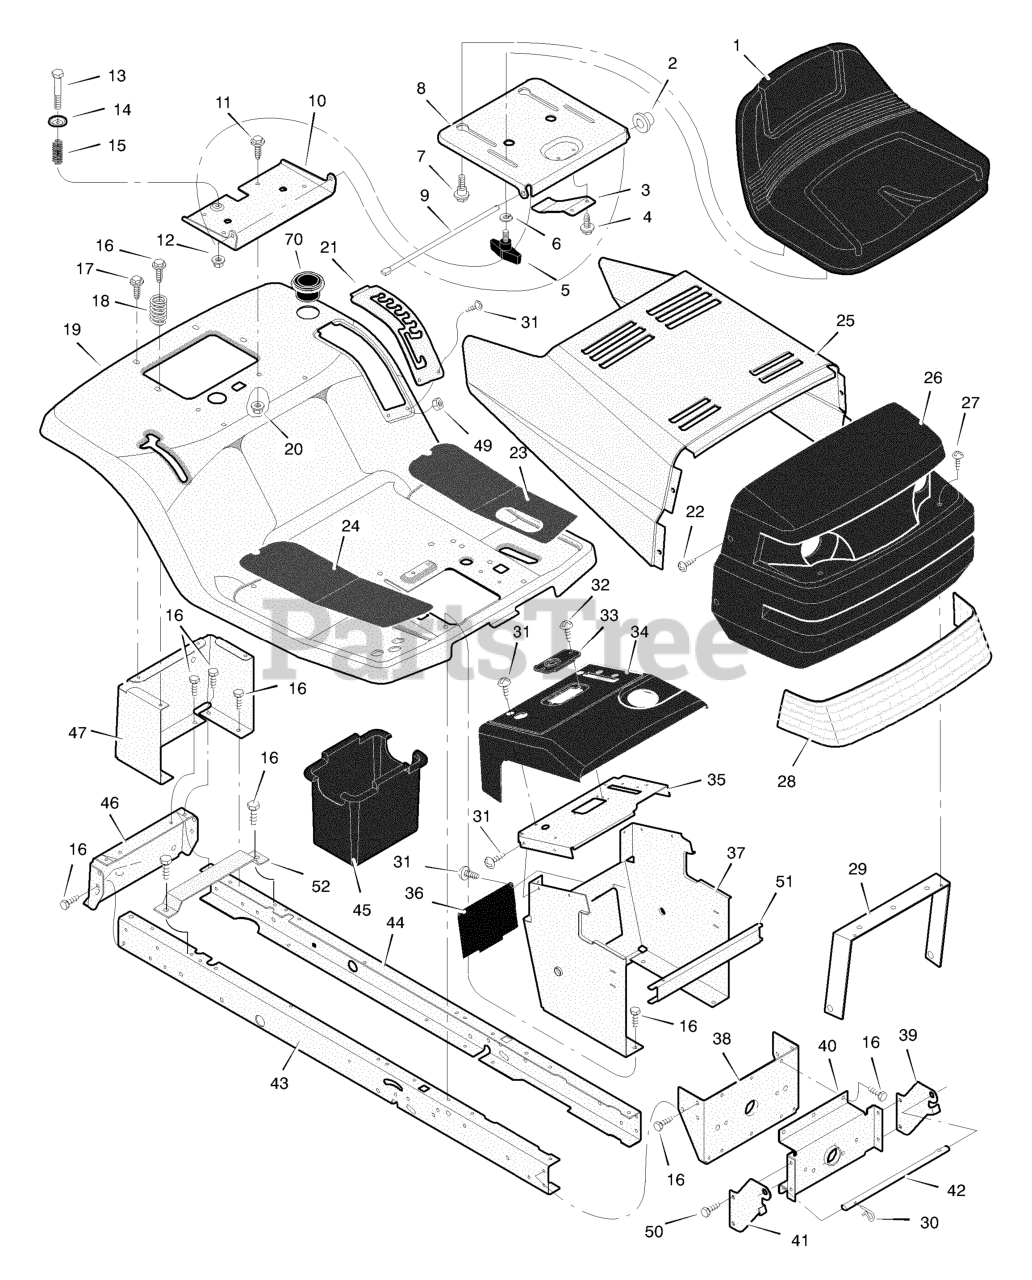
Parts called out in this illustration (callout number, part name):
2	Cap, Push On
5	Bolt, Wing
6	Washer
7	Bolt, Shoulder
8	Support, Seat
9	Rod, Pivot
10	Bracket, Pivot
11	Bolt
13	Bolt, Shoulder
15	Spring
19	Deck, Seat
20	Nut
21	Plate, Index
23	Mat, Left
24	Mat, Right
26	Grille Assembly
27	Screw
28	Lens
29	Brace, Grille
30	Pin, Hair
31	Screw
33	Bearing, Steering
35	Plate, Dash
36	Panel, Access
37	Support, Dash
38	Bracket, Rear Hanger
39	Support, Left Grille
40	Axle, Hanger
41	Support, Right Grille
42	Rod, Pivot
43	Frame, Right
44	Frame, Left
45	Container, Battery
46	Plate, Hitch
47	Panel, Rear
52	Support, Battery
70	Holder, Cup
